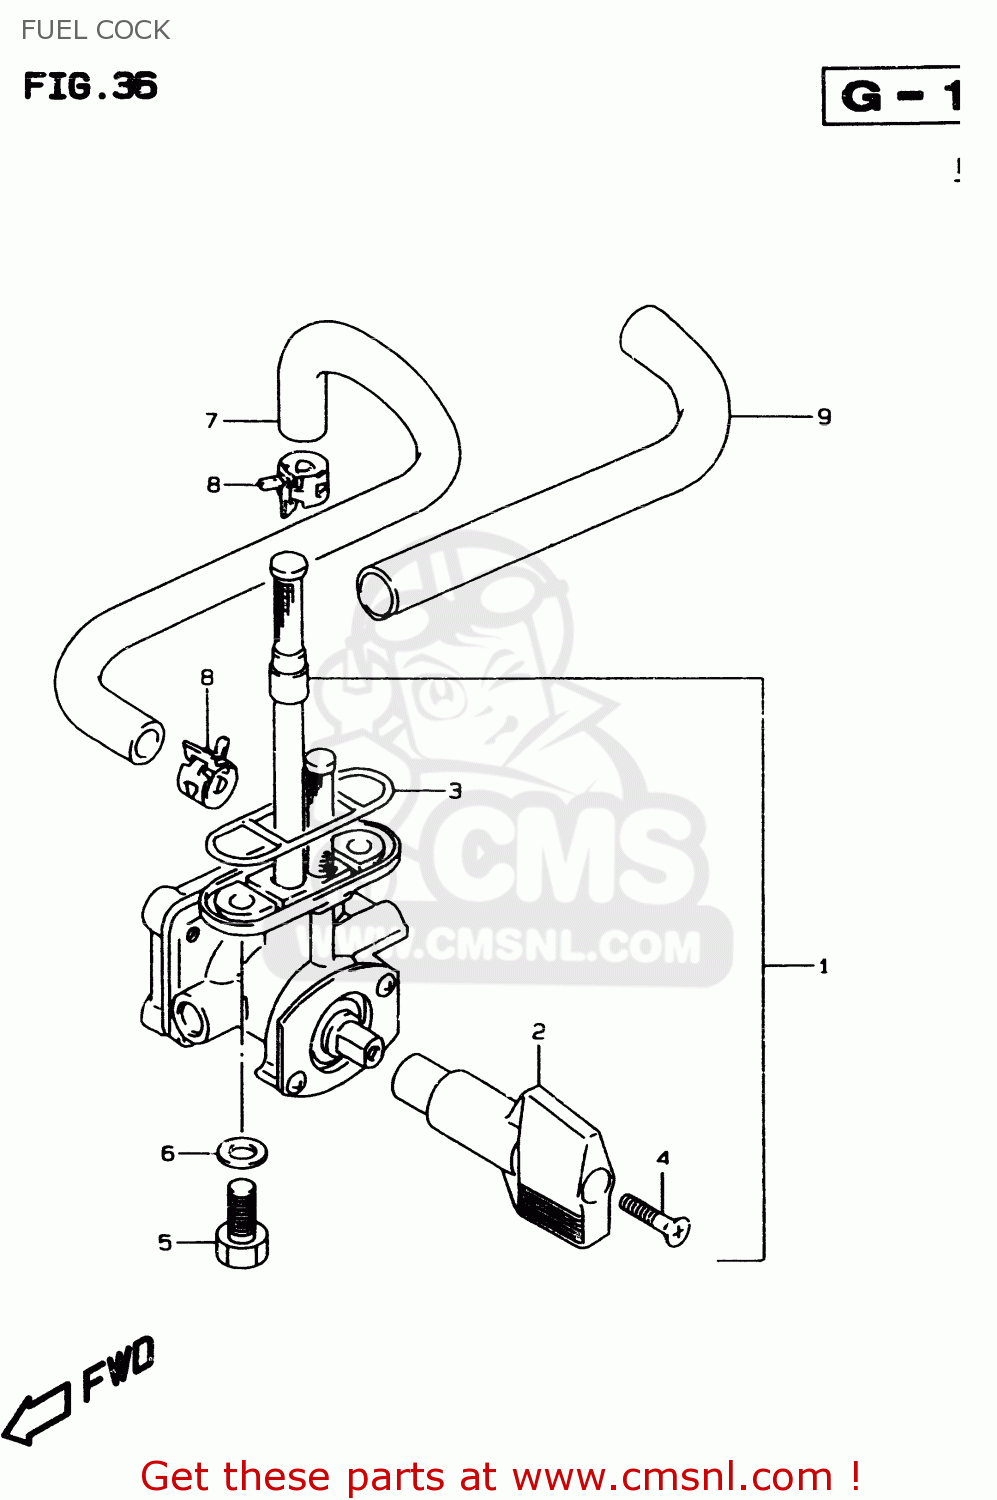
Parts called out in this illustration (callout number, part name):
1	COCK ASSEMBLY,FUEL
2	LEVER,FUEL COCK
3	GASKET,JOINT (NAS)
4	SCREW
5	BOLT(6X20)
6	GASKET(6.4X11.5X0.8) (NAS)
7	HOSE(7X12X600)
8	CLIP
9	PROTECTOR(14.5X15.5X600)
